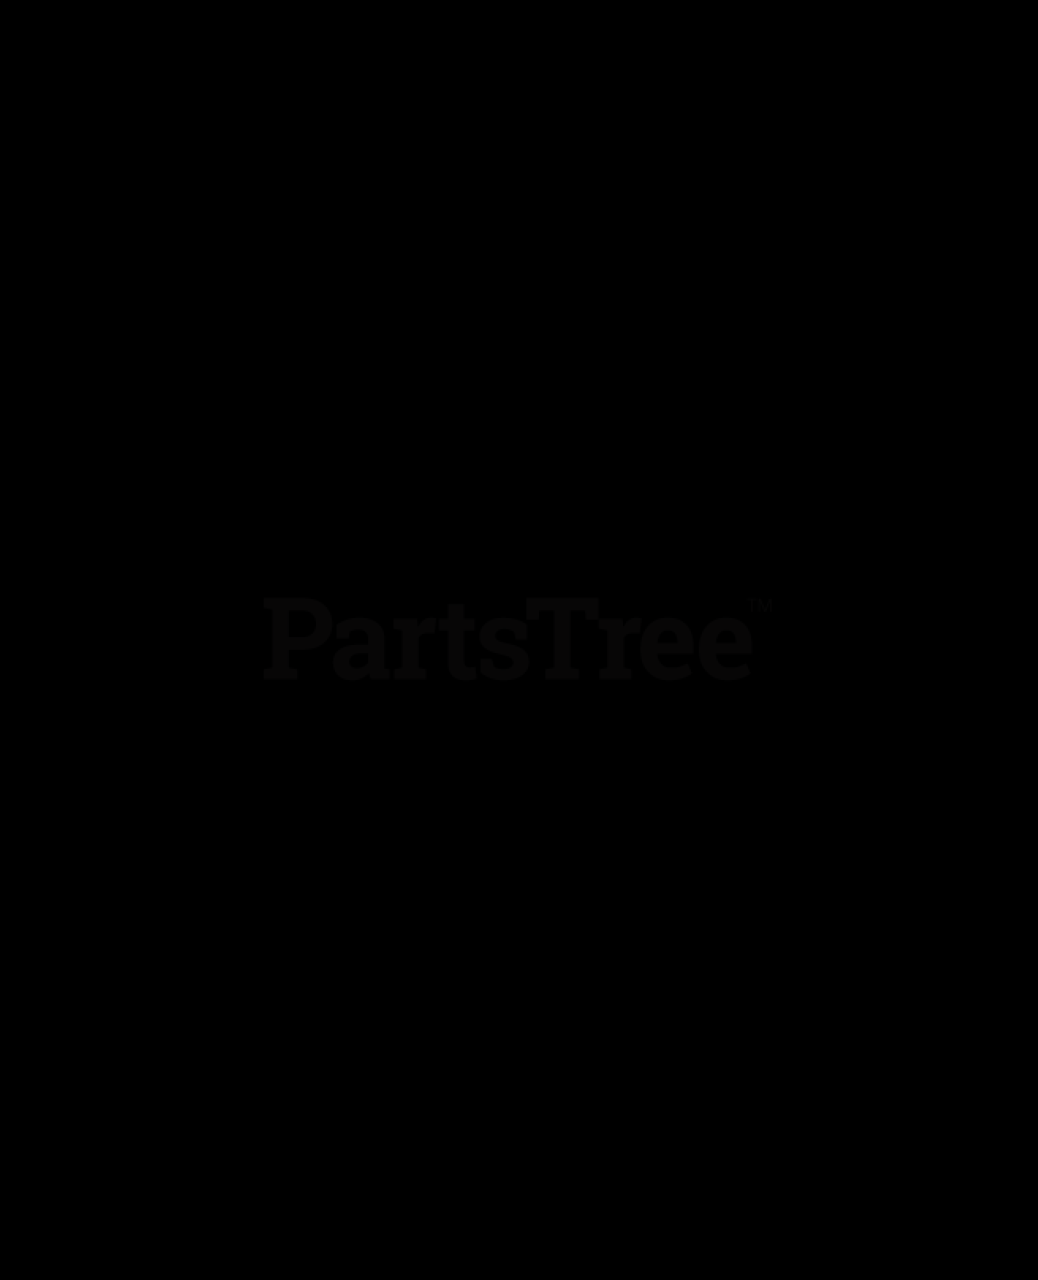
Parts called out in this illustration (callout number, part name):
1	Head, Filter
2	Bolt, Hex .25-20 x .50 Grade 5 Epoxy
3	Filter Element
4	Body, Hydraulic Tank
5	Breather, Dipstick
6	Fitting, Hydraulic, Straight
7	Screw, Tapping .38-16 x .75 Hex Washer Head
8	Fitting, Hydraulic, 90 Degree Elbow
9	Hose, Hydraulic Valve to Tank
10	Hose, Hydraulic, 10-inch
11	Fitting, Hydraulic, 90 Degree Elbow
12	Hose, Hydraulic .50, 5-Inch
13	Fitting, Hydraulic Tee
14	Hose, Hydraulic, 16-inch
15	Fitting, Hydraulic (4 F5OLO)
